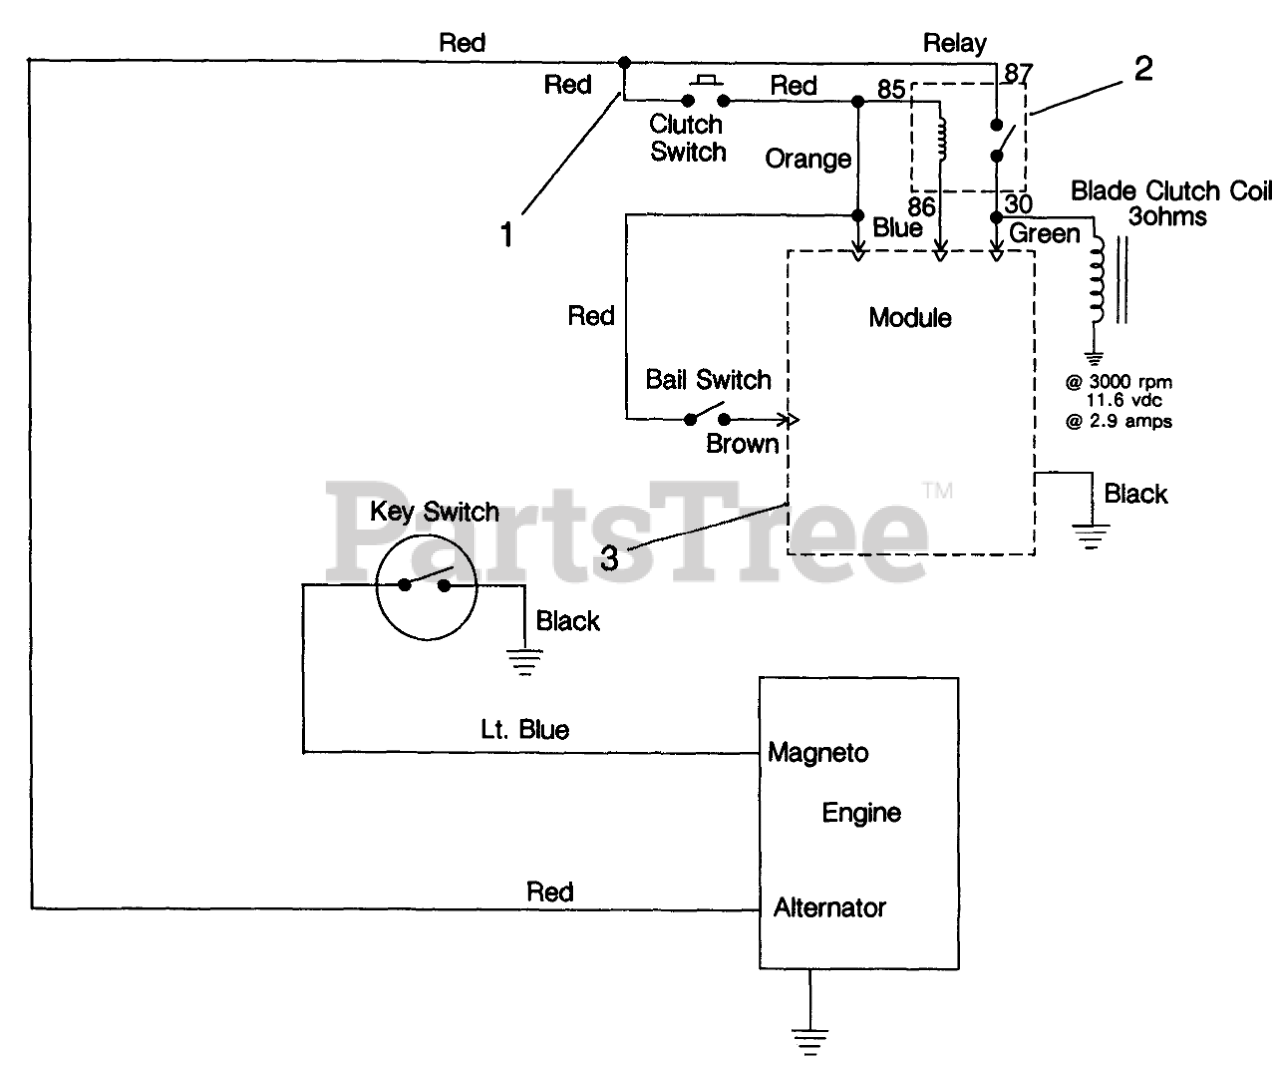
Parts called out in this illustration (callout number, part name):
1	WIRE HARNESS
2	Relay
3	Module
